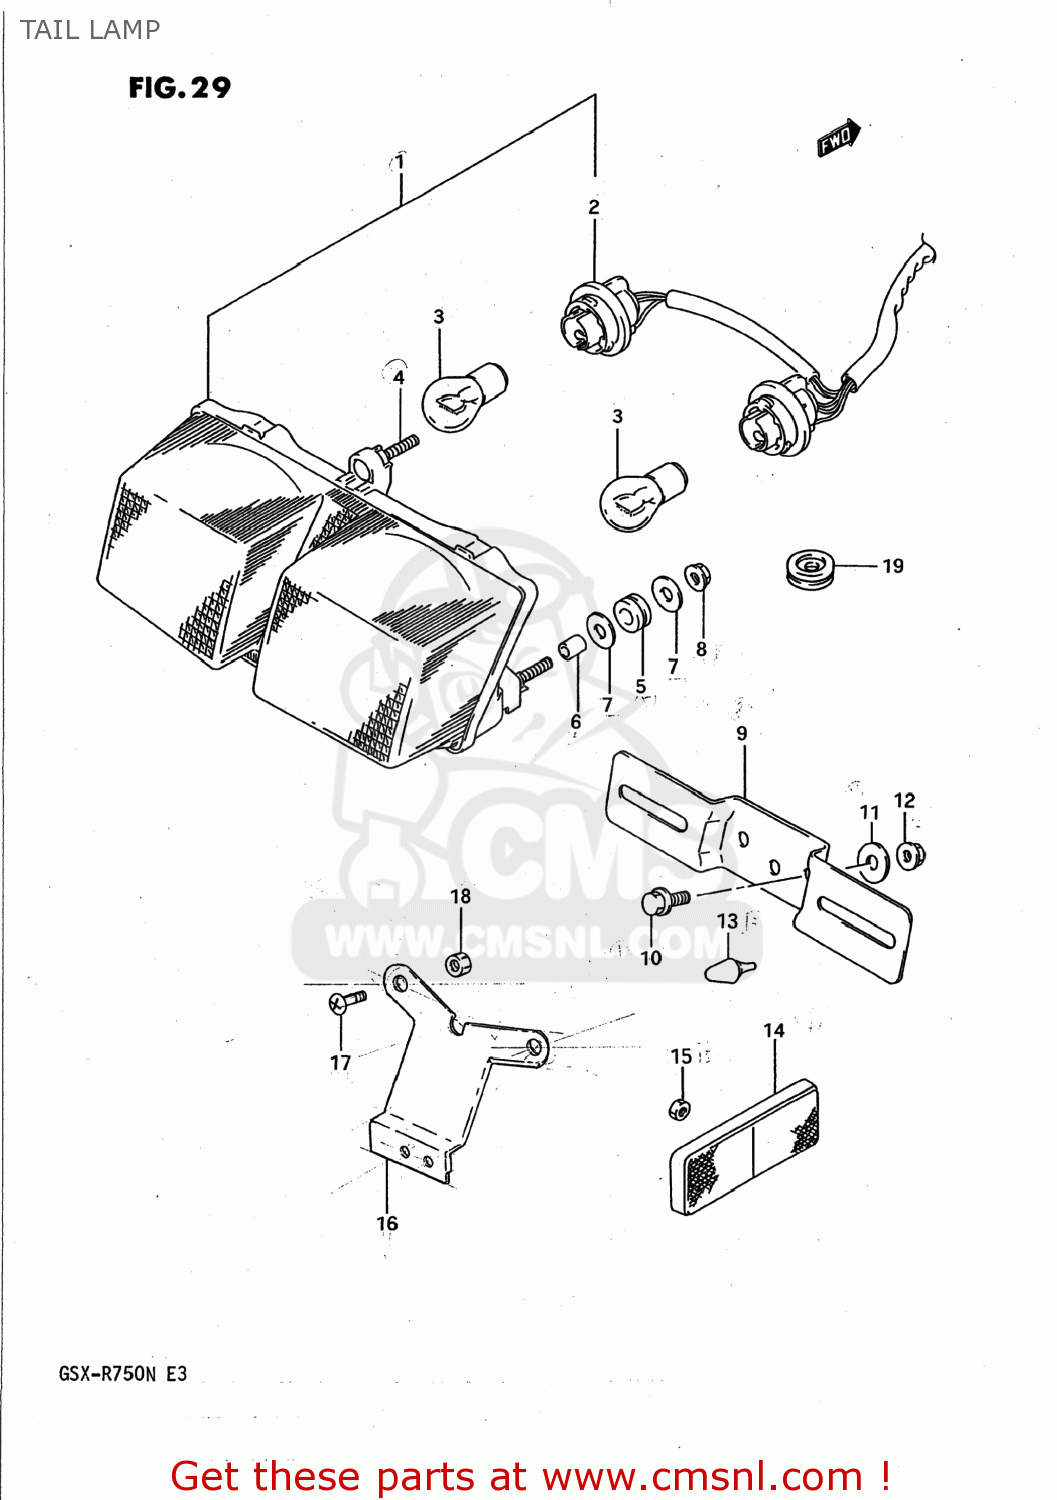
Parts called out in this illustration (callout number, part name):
1	LAMP ASSEMBLY,REAR COMBINATION
2	SOCKET ASSEMBLY
3	BULB(12V21/5W)
4	BOLT 6X30
5	CUSHION
6	SPACER (6.1X8X9.5)
7	WASHER(6.5X18X1)
8	NUT
9	BRACKET,LICENSE PLATE
10	BOLT
11	WASHER,COVER,FRONT
12	NUT
13	CUSHION
14	REFLECTOR ASSEMBLY,REAR
15	NUT 5MM
16	BRACKET,REAR,REAR
17	SCREW 6X12
18	NUT
19	GROMMET
